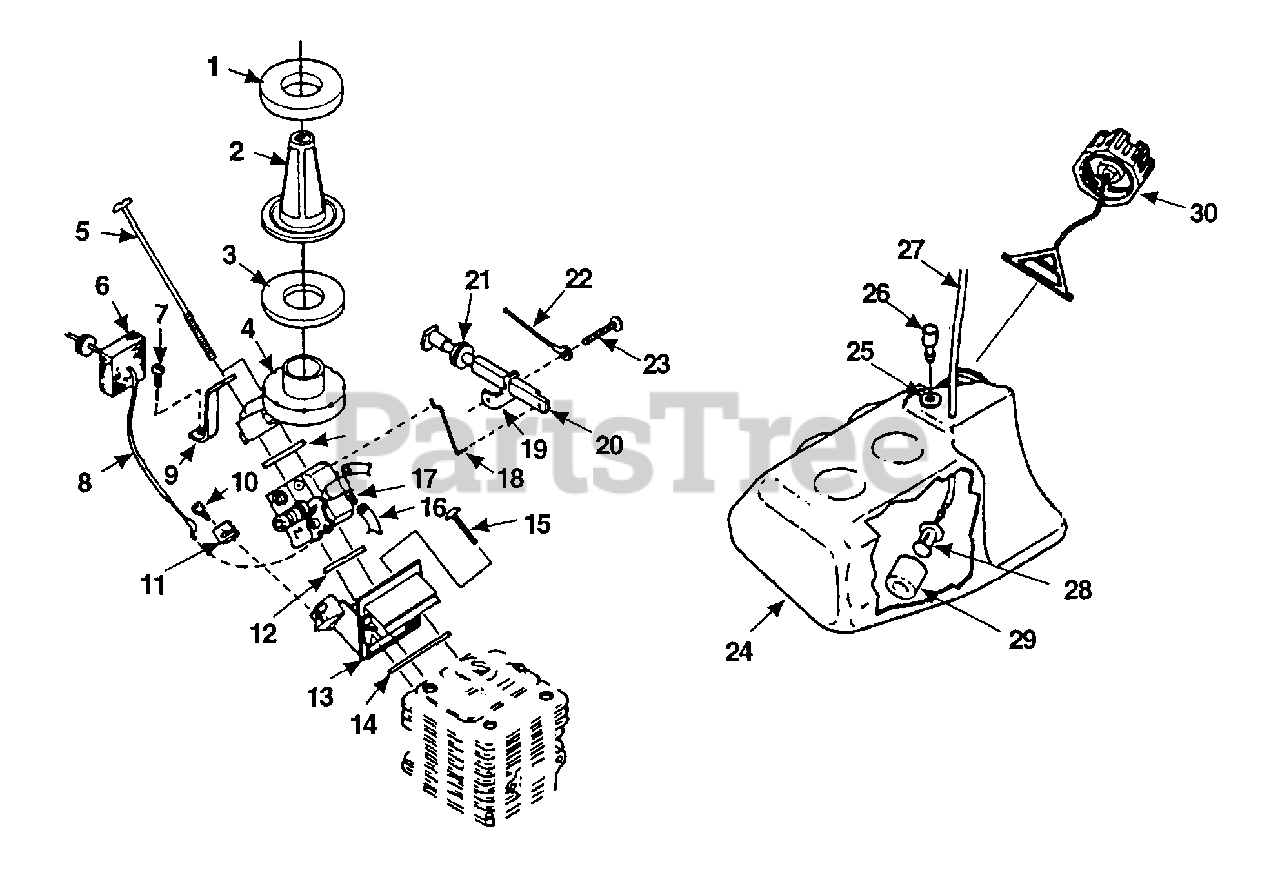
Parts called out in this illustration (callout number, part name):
1	GASKET-Foam (1/4")
2	FILTER-Screen
3	GASKET Foam
4	ADAPTOR-Intake
5	SCREW-Truss Hd. (8-16 X 3 1/4")
6	PAD-Foam
7	SCREW-Torx (10-24 X 1/2")
8	CABLE-Throttle
9	BRACKET-Air Intake
10	SCREW-Thread Form. (6-19 X 1/2")
11	BRACKET-Cable End
12	GASKET-Carburetor
13	ADAPTOR-Intake
14	GASKET-Adaptor
15	SCREW-Pan Hd. (10-24 X 1")
16	TUBING,Pulse line (4 3/4")
17	CARBURETOR-Walbro
18	CHOKE LINK & RETAINER
19	BRACKET-Cable
20	ROD-Choke
21	GROMMET
22	GROUND WIRE
23	SCREW-Truss Hd. (10-24 X 1 1/4")
24	TANK-Fuel
25	GROMMET
26	FILTER SLEEVE
27	TUBING-Rubber (10")
28	FILTER-Fuel
29	FILTER-Fuel
30	CAP-Tank (w/Retainer)
